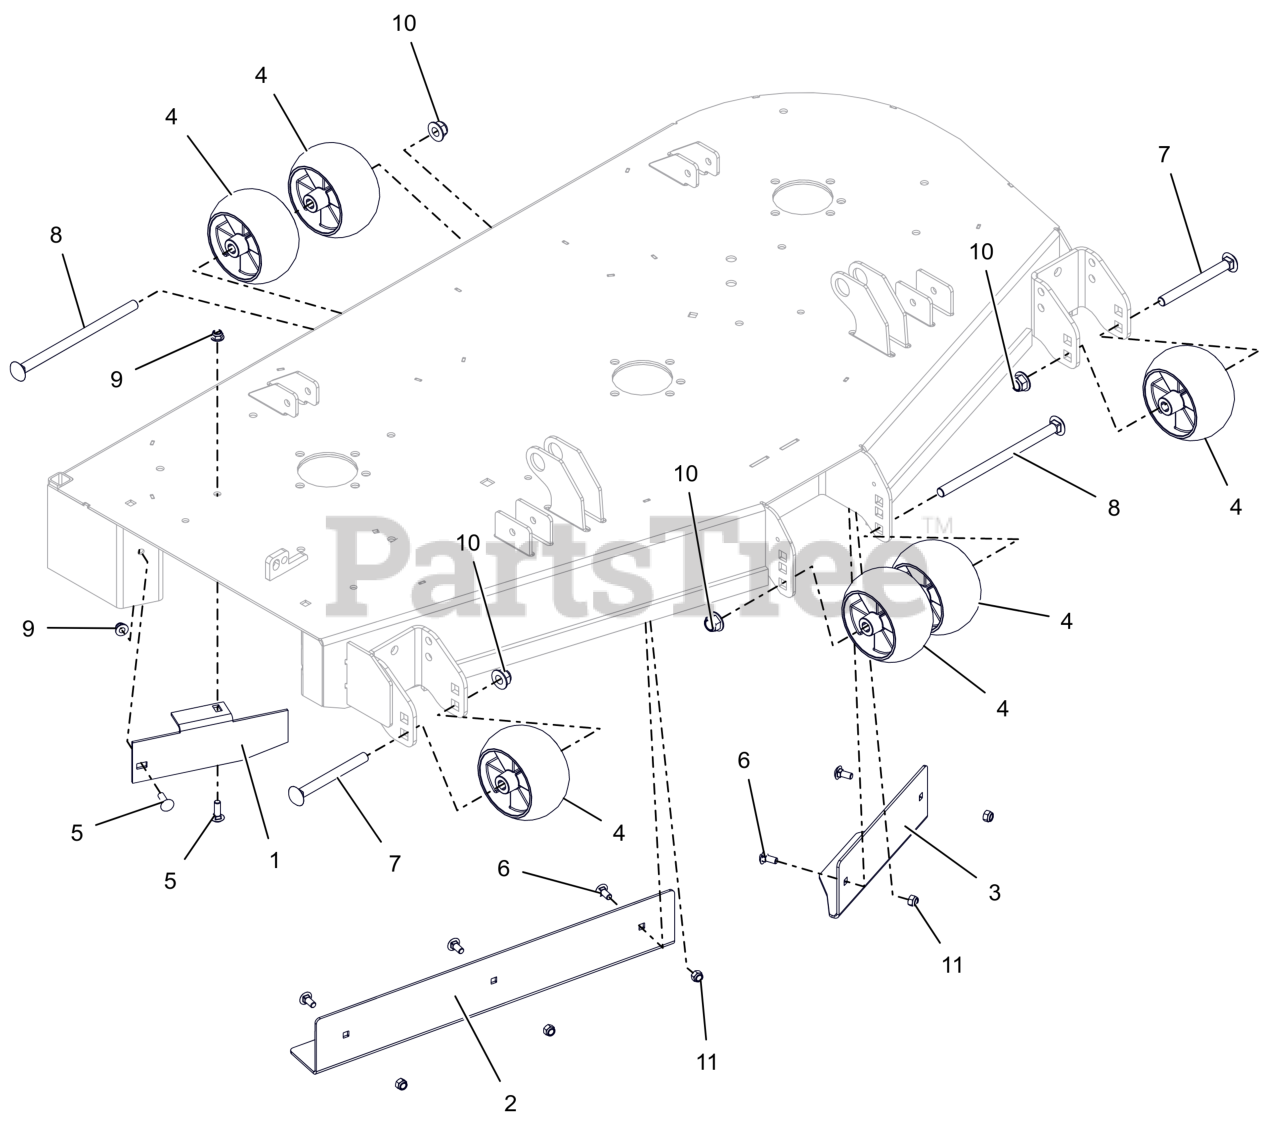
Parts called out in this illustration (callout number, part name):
1	BAFFLE, DISCHARGE, 52"
2	BAFFLE, 52" RH VACUUM (ORANGE)
3	BAFFLE, 52" LH VACUUM (ORANGE)
4	WHEEL, ANTI SCALP - 5X3 CTR W/RIBS
5	BLT,RHSN .31-18X1.00 G5 ZCC
6	BLT,RHSN .31-18X.75 G5 ZCC
7	BLT, RHSN .50-13X5.00 G5 ZCC
8	BTL,RHSN .500-13 X 8.5S G5 ZCC
9	NUT,LK-NYL-FLG .31-18 G5ZC120
10	NUT,NYL-FLG .50-13 GF ZCC
11	NUT,NYL .31-18 G5 ZCC
